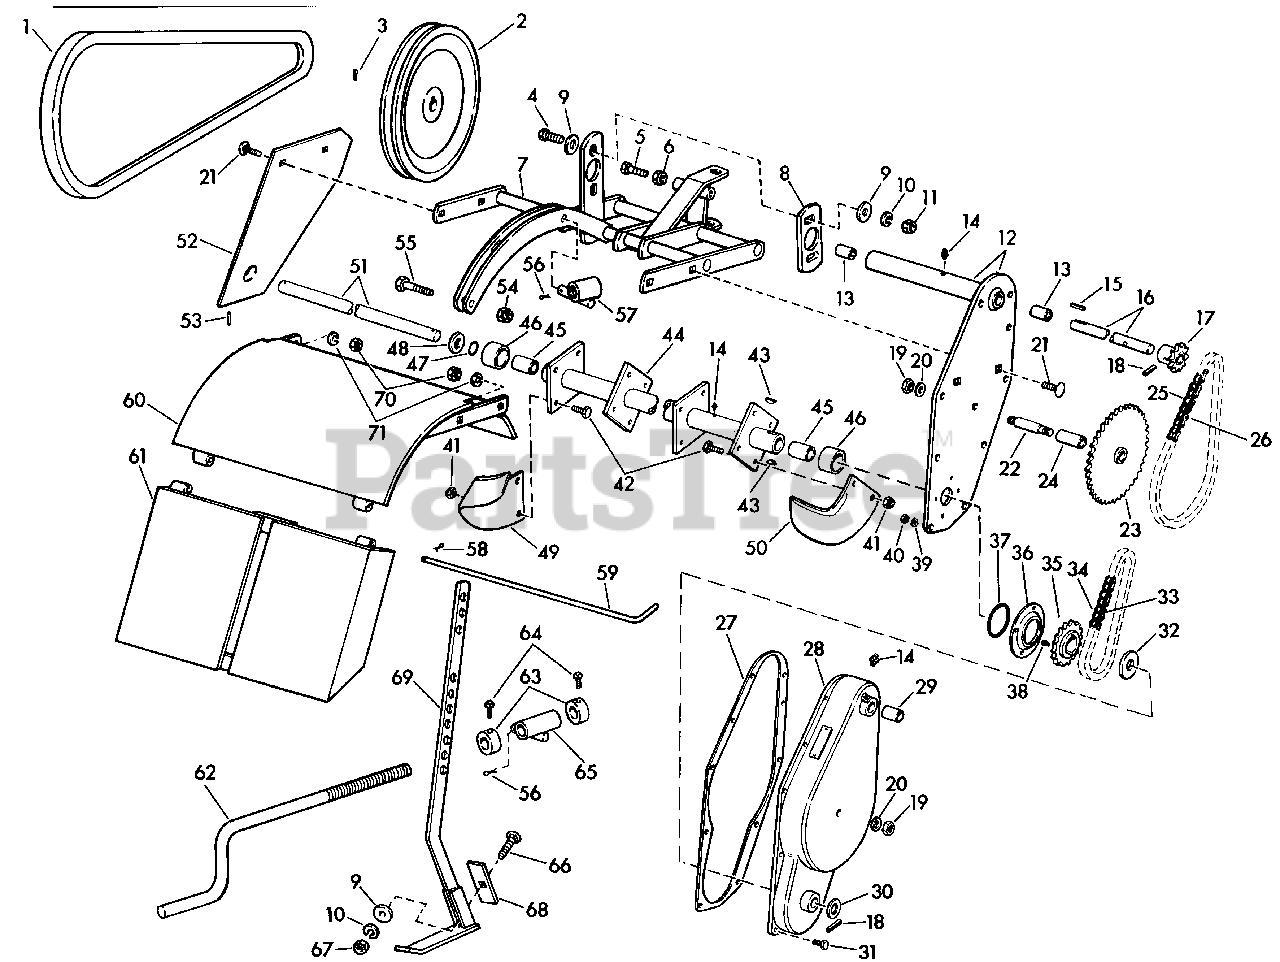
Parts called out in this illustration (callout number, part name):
1	"V" Belt 60" A Section
2	Pulley 10.4 OD A Section
3	Set Screw 5/16-18
4	Capscrew 5/16-18 x 7/8 Lg.
5	Capscrew 3/8-16 x 1 Lg.
6	Hex Nut 3/8-16
7	Frame Assembly
8	Adjustable Guide
9	Washer 5/16
10	Lockwasher 5/16
11	Hex Nut 5/16-18
12	Back Plate Assembly
13	Bushing (Oilite)
14	Grease Fitting 1/4-28 St.
15	Key 3/16 Sq. x 3/4 Lg.
16	Input Shaft
17	Input Sprocket and Hub Assembly
18	Roll Pin 3/16 x 1-1/8 Lg.
19	Jam Nut 1/2 x 20
20	Lockwasher 1/2 Internal Shakeproof
21	Carriage Bolt 3/8-16 x 1 Lg.
22	Intermediate Shaft
23	Sprocket Cluster Assy
24	Bushing
25	Chain #41-1/2 Pitch, 55 Links
26	Connector Link
27	Side Plate Gasket
28	Cover Assembly
29	Bushing
31	Capscrew 1/4-20 x 5/8 Lg.
32	Thrust Washer
33	Chain #40-1/2 Pitch, 37 Links
34	Connector Link
35	Sprocket 18 Tooth
36	Oil Seal Retainer
37	"O" Ring (Neoprene)
38	Self Tapping Screw #8-32 x 1/4 Lg.
39	Lockwasher 1/4 Internal Shakeproof
40	Hex Nut 1/4-20
41	Marsden Nut 3/8-24
42	Tine Bolt 3/8-24 NF x 3/4 Lg.
43	Woodruff Key
44	Rotor Tube Assembly
45	Bushing
47	"O" Ring
48	Thrust Washer
49	Tine LH
50	Tine RH
51	Rotor Shaft
52	Side Plate Assembly
53	Roll Pin 3/16 x 1-3/4 Lg.
54	Locknut 3/8-24, Marsden
55	Capscrew 3/8-24 x 2 Lg.
56	Cotter Pin 1/8 x 1-1/2 Lg.
57	Adjusting Screw Nut
58	Cotter Pin 3/32 x 3/4 Lg.
59	Hinge Rod
60	Hood Assembly
61	Hood Board Assembly
62	Adjusting Screw
63	Set Collar 5/8 ID
64	Set Screw 5/16-18
65	Bearing Assembly
66	Carriage Bolt 5/16-18 x 1-3/4 Lg.
67	Hex Nut 5/16-18
68	Adjustable Shovel
69	Depth Shoe Assembly
70	Hex Nut 3/8-16
71	Lockwasher
